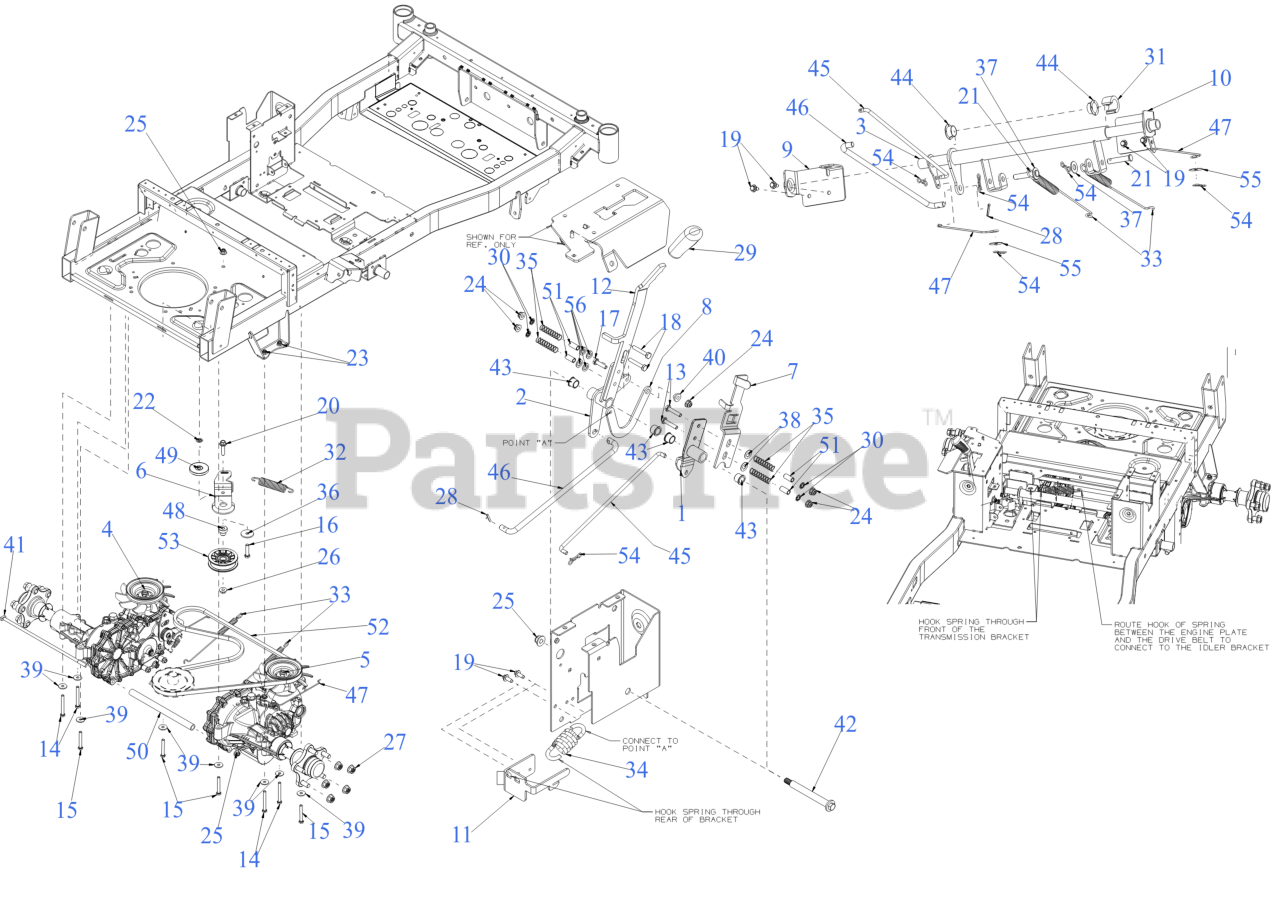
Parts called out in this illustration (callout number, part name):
1	BYPASS LEVER PIVOT ARM
2	PARK BRAKE PIVOT ARM
3	BRAKE PIVOT SHAFT
4	HYDRO TRANSMISSION (LH)
5	HYDRO TRANSMISSION (RH)
6	HYDRO DRIVE IDLER BRACKET
7	TRANSMISSION BYPASS LEVER
8	OVER CENTER LINK
9	BRAKE SHAFT SUPPORT (RH)
10	BRAKE SHAFT SUPPORT (LH)
11	SPRING MOUNTING BRACKET
12	PARK BRAKE LEVER
13	HEX SCREW 1/4-20 x 1.25
14	HEX SCREW 5/16-18 x 2.75
15	HEX SCREW 5/16-18 x 2.25 GR5
16	SCREW 3/8-16 x 1.50
17	SCREW 1/4-20 X1.00 GR5
18	SCREW 1/4-20 x 1.50 GR.5
19	SCREW M6-1 x .625
20	HEX HEAD BOLT (3/8-16:1.50 GR8)
21	CLEVIS PIN 3/8 x 1.87
23	FLANGE LOCK NUT 5/16-18
24	FLANGE LOCK NUT
26	FLANGE LOCK NUT
27	HEX FLANGE NUT 1/2-20 GR8
28	COTTER PIN
30	RETAINER-BOLT .25ID x .50OD
31	SPACER: .76ID x .75
32	EXTENSION SPRING .925 x 5.37
33	EXTENSION SPRING .60 DIAx9.09
34	EXTENSION SPRING 1.09x3.25
35	COMPRESSION SPRING
36	FLAT WASHER .390x1.500x.134
37	FLAT WASHER
38	WASHER THRUST .375X.70X.030
39	FLAT WASHER 1.0 OD:.331 ID
40	SHOULDER SPACER
41	SUPPORT TUBE ROD
42	SHOULDER SCREW .491x3.937 3/8-16
43	FLANGE BUSHING
44	FLANGE BEARING .75 x 1.125 x .375
45	BYPASS LINK
46	BRAKE LINK
47	HYDRO BYPASS ROD .100 DIA
48	SHOULDER SPACER
49	SHOULDER SPACER
50	SUPPORT TUBE
51	SPACER .252x.350x.760
52	TRANSMISSION DRIVE BELT A x 67
53	FLAT IDLER PULLEY 3.00 OD
54	BOW TIE COTTER PIN 1/4-5/16
55	FLAT WASHER
56	FLAT WASHER
